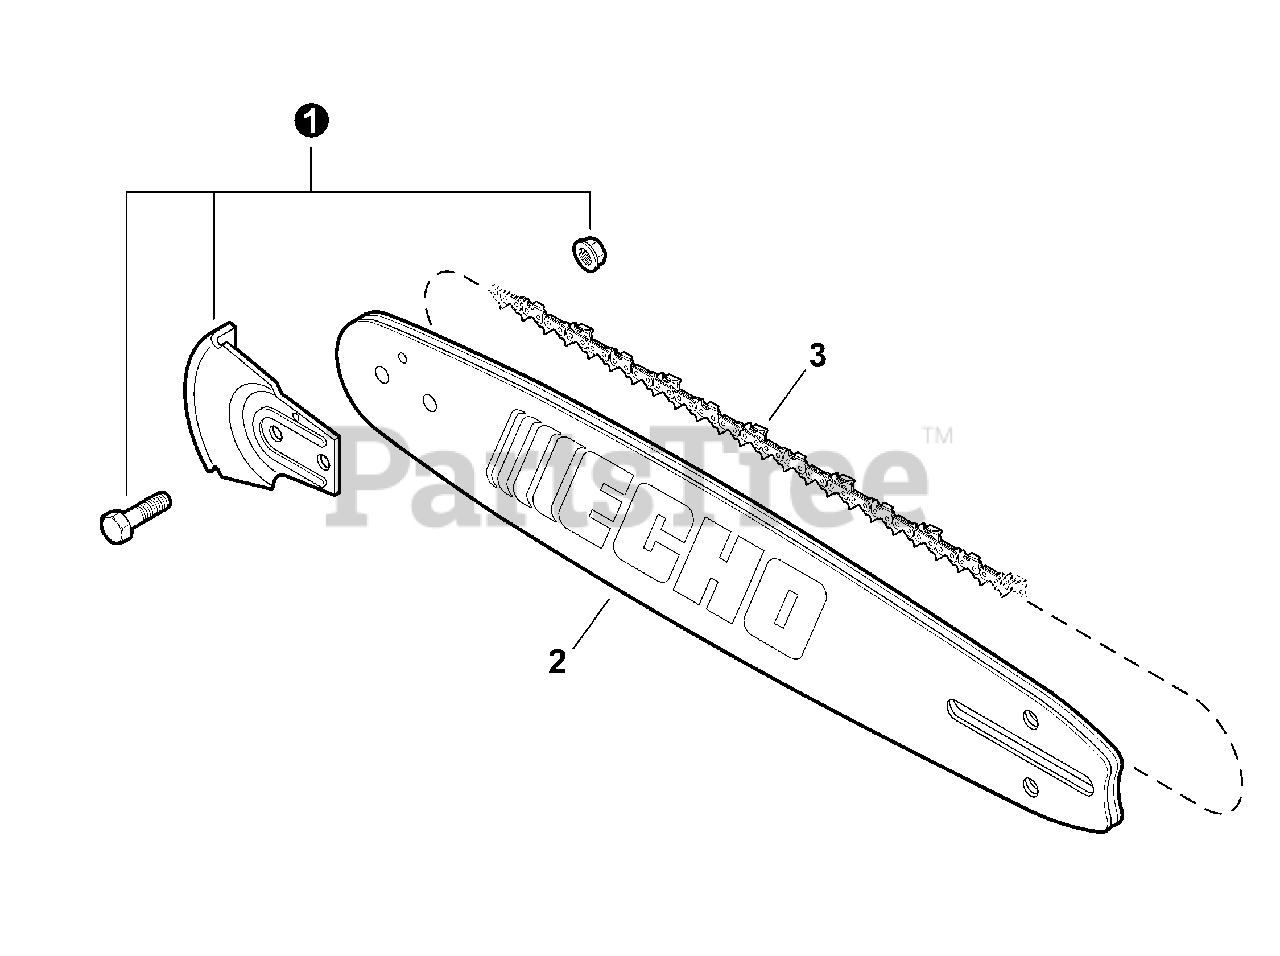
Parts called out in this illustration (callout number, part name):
1	KICK GUARD KIT
2	GUIDE BAR, 16" POWER MATCH
2	GUIDE BAR, 18" POWER MATCH
2	GUIDE BAR, 20" POWER MATCH
2	GUIDE BAR, 24" POWER MATCH
2	GUIDE BAR, 27" POWER MATCH
3	SAW CHAIN - 16"
3	SAW CHAIN - 18"
3	SAW CHAIN - 20"
3	SAW CHAIN - 24"
3	SAW CHAIN - 27"
